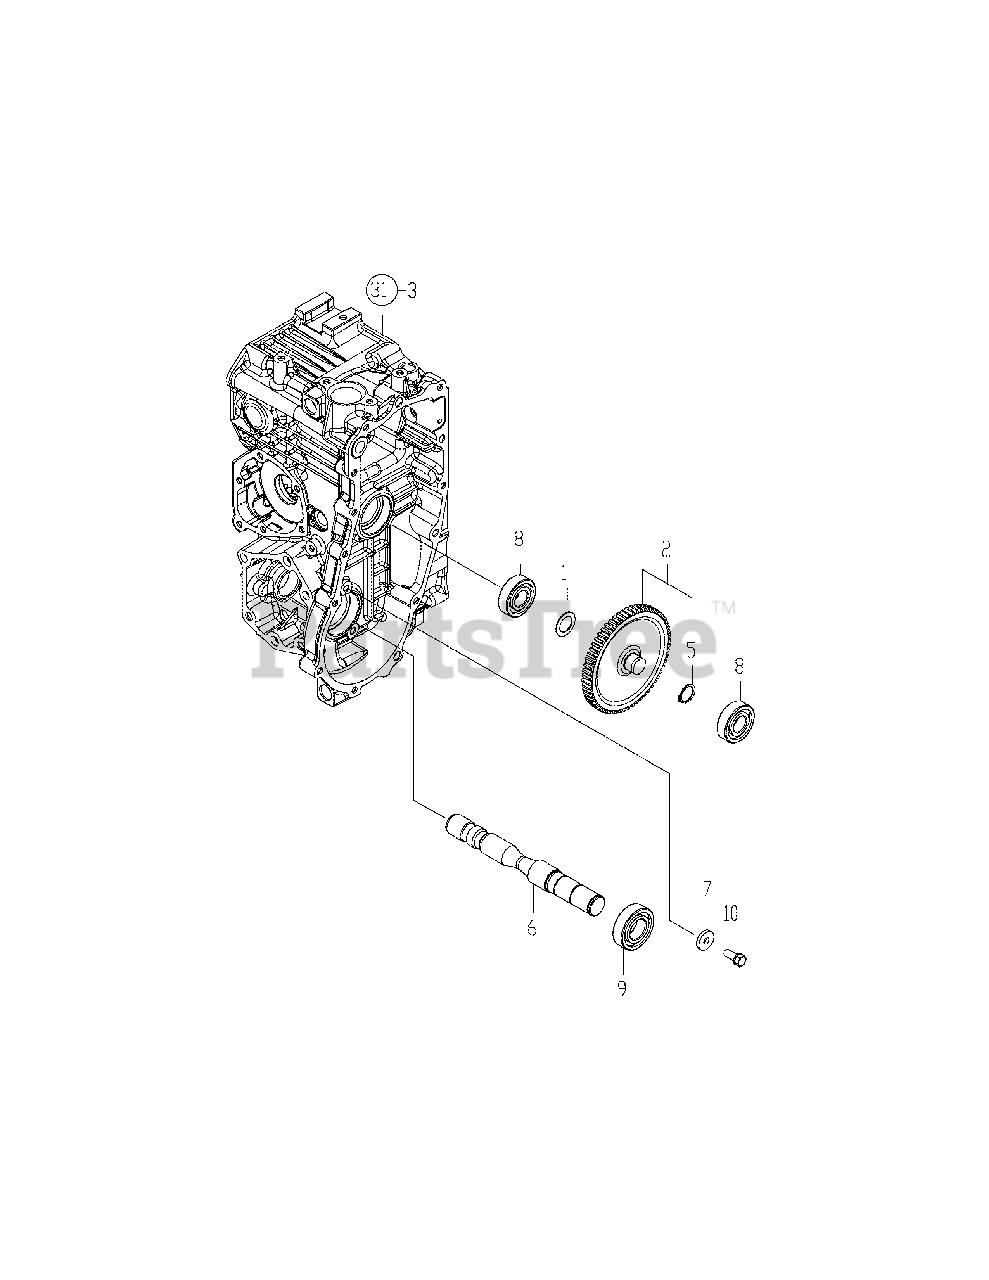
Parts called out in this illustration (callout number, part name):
2	Idle Assy, Pto
6	Shaft, Mid Pto
7	Washer, 8.5X24X4
9	Bearing, 6205 Ntn
